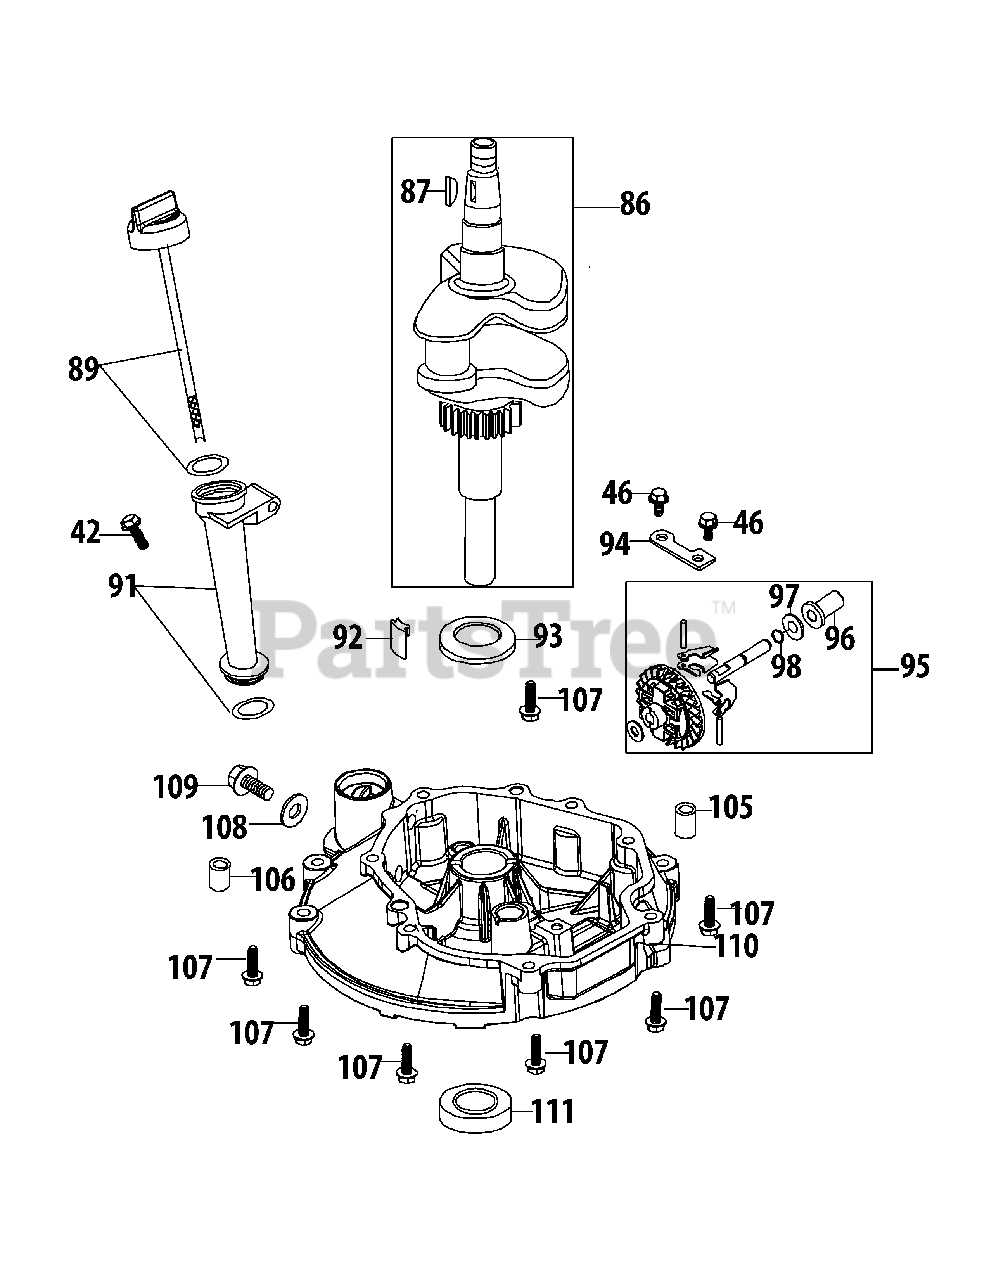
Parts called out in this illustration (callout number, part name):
42	Bolt M6X35 Af Base/Brake/Dipstick
46	Bolt M6X14 Multi-Purpose
86	Crankshaft Assembly
87	Flywheel Key
91	Oil Fill Tube
92	Oil Return Seal
93	Crankshaft Thrust Washer
94	Governor Gear Mounting Plate
95	Governor Gear/Shaft Assembly
96	Governor Slide Cap
97	Governor Slide Cap Washer
98	Governor Shaft Stop Ring
105	Crankcase Cover Dowel Pin F7×14
106	Crankcase Cover Dowel Pin F9×14
107	Bolt M6X28 T/X/P Multi-Purpose/Crankcase
108	Oil Drain Plug Washer
109	Oil Drain Plug
110	Crankcase Cover
111	Lower Crankshaft Seal
